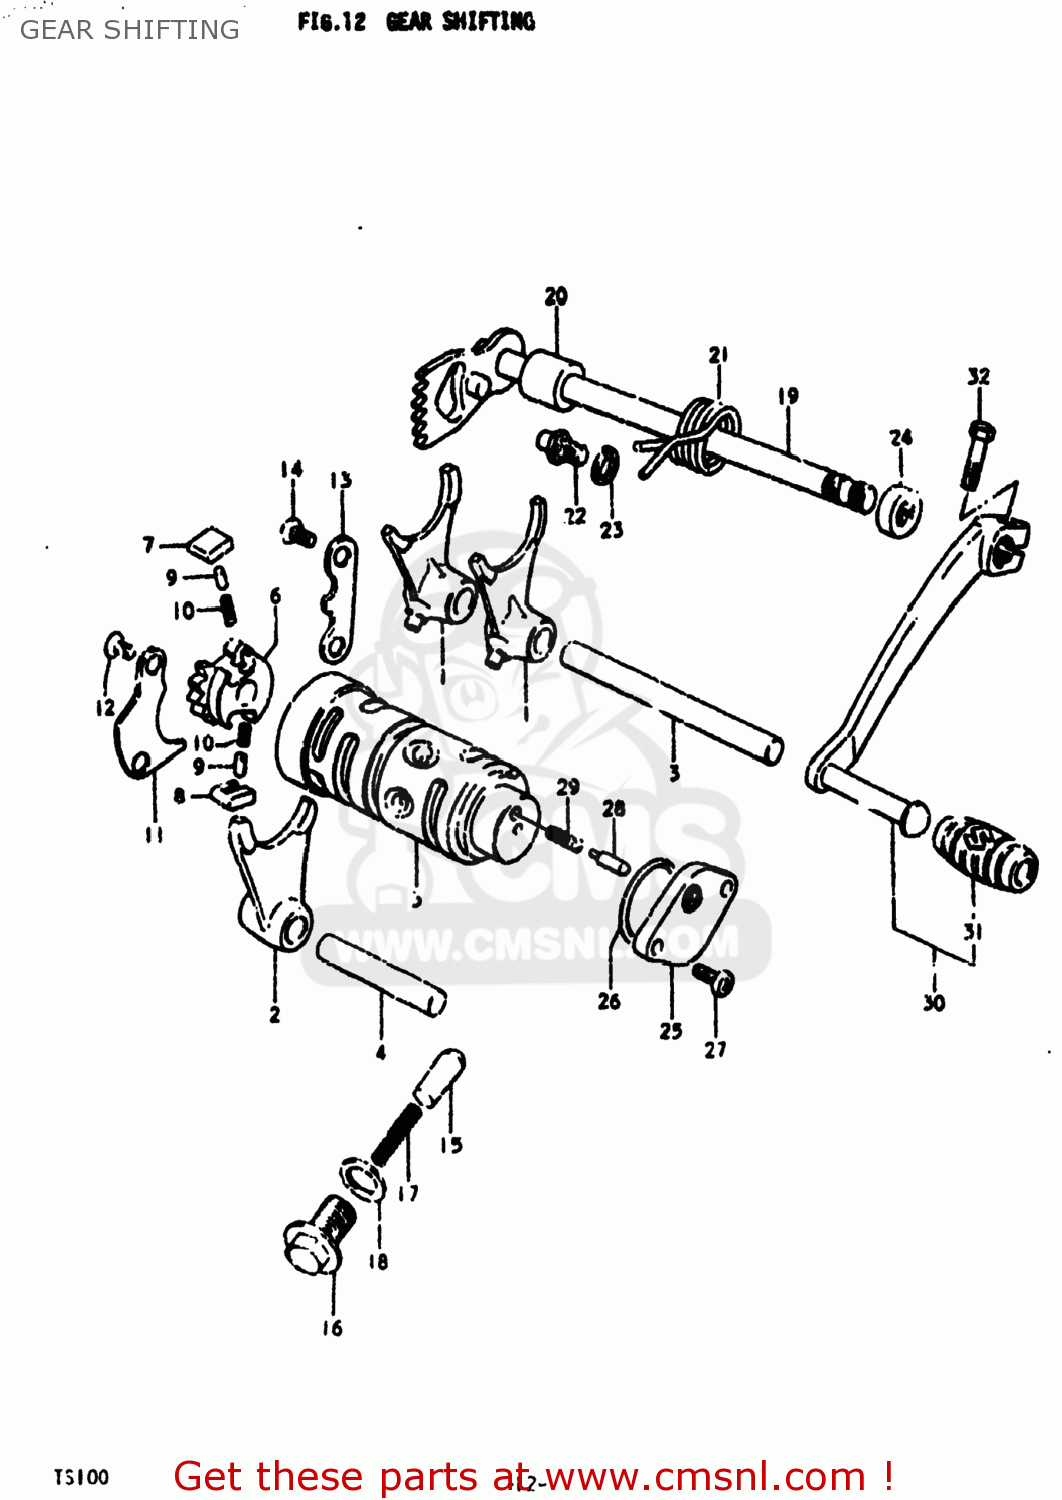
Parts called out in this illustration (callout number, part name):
1	FORK,GEAR SHIFT NO.1
2	FORK,GEAR SHIFT NO.2
3	SHAFT,GEAR SHIFT FORK
4	SHAFT,GEAR SHIFT FORK
5	CAM,GEAR SHIFT
6	RETAINER,GEAR SHIFT CAM
7	PAWL,GEAR SHIFT NO.1
8	PAWL,GEAR SHIFT NO.2
9	PIN(5X8)
10	SPRING
11	LIFTER,GEAR SHIFT PAWL
12	SCREW
13	GUIDE,GEAR SHIFTING CABLE
14	SCREW
15	STOPPER,GEAR SHIFTING
16	BOLT,GEAR SHAFT CAM STOPPER
17	SPRING
18	GASKET(14X19.2X2) (NAS)
19	SHAFT,GEAR SHIFT
20	SPACER(12X20X15.3)
21	SPRING
22	STOPPER,GEAR SHIFT CAM
23	WASHER
24	OIL SEAL
25	BODY,GEAR SHIFT SWITCH
26	O-RING (D:2.4 ID:26.2)
27	SCREW
28	PIN(5X15.5)
29	SPRING
30	LEVER ASSY,GEAR SHIFT
31	RUBBER,GEAR SHIFT PEDAL
